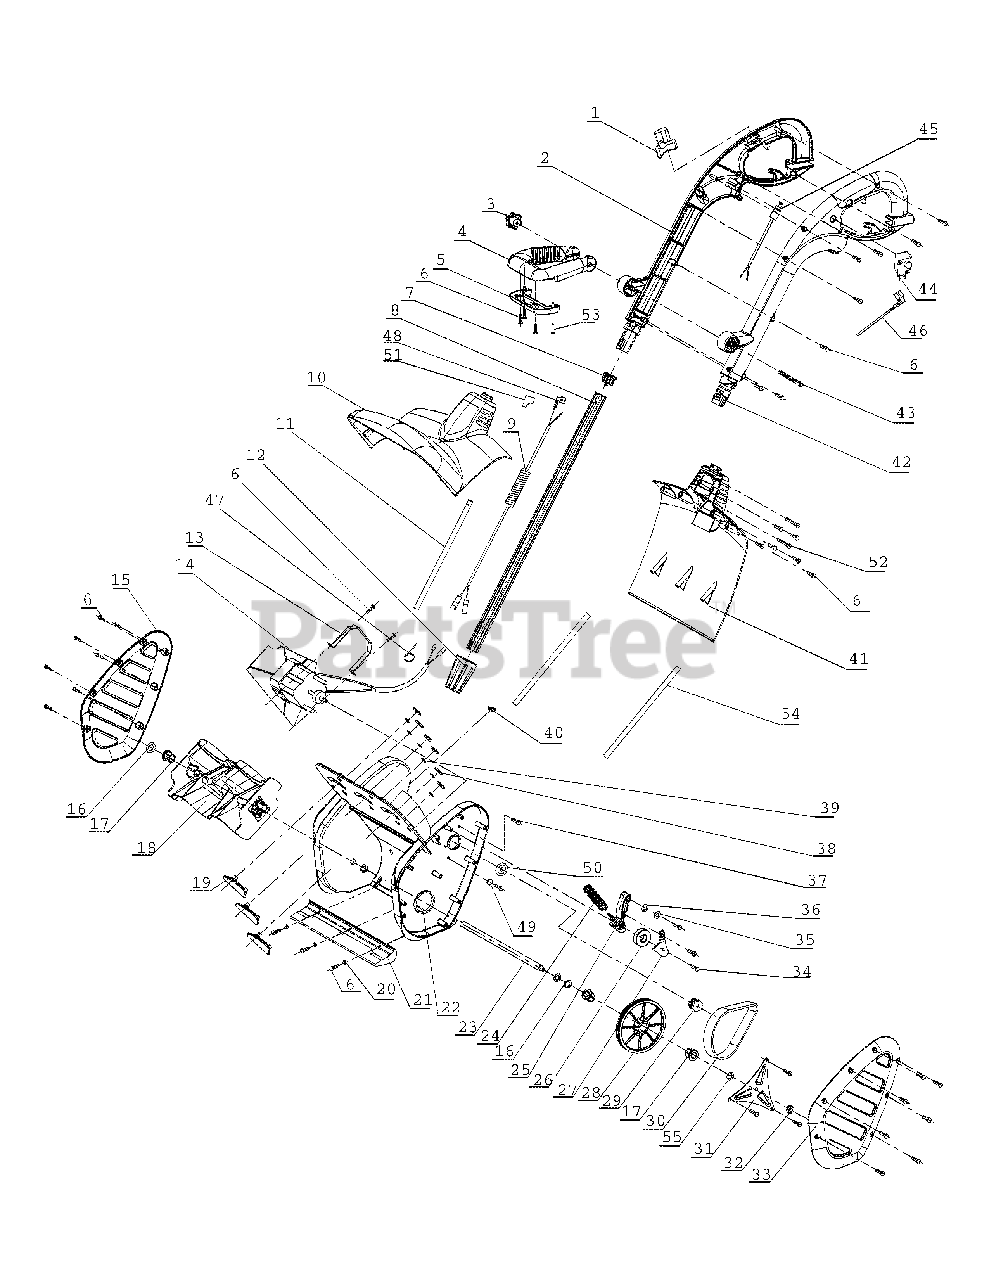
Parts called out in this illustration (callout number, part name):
1	SWITCH
2	HANDLE RIGHT
3	KNOB
4	ASSIST HANDLE
5	ASSIST HANDLE
6	SCREW
7	PLUG PIPE
8	TUBE
9	SPRING CODE
10	HOUSING TOP
11	PIPE
12	SPOOL
13	FIXED PLATE
14	MOTOR
15	COVER RIGHT
16	WASHER
17	SLEEVE
18	BLADE
19	PLATE
20	WASHER
21	PLATE
22	MAIN BODY
23	SHAFT
24	SPRING
25	HOLDER BOTTOM
26	BEARING
27	HOLDER TOP
28	PULLEY
29	PULLEY ACTIVE
30	STRAP
31	FIXED PLATE
32	NUT
33	COVER LEFT
34	SCREW
35	WASHER
36	WASHER
37	SCREW
38	WASHER
39	WASHER
40	CAP
41	HOUSING BOTTOM
42	HANDLE LEFT
43	SCREW
44	PROTECT SWITCH
45	CONNECTOR
46	WIRE ASS'Y
47	BAND, PLASTIC
48	TERMINAL
49	WASHER
50	PLASTIC WASHER
51	PIPE
52	SCREW
53	SCREW
54	GASKET
55	WASHER
